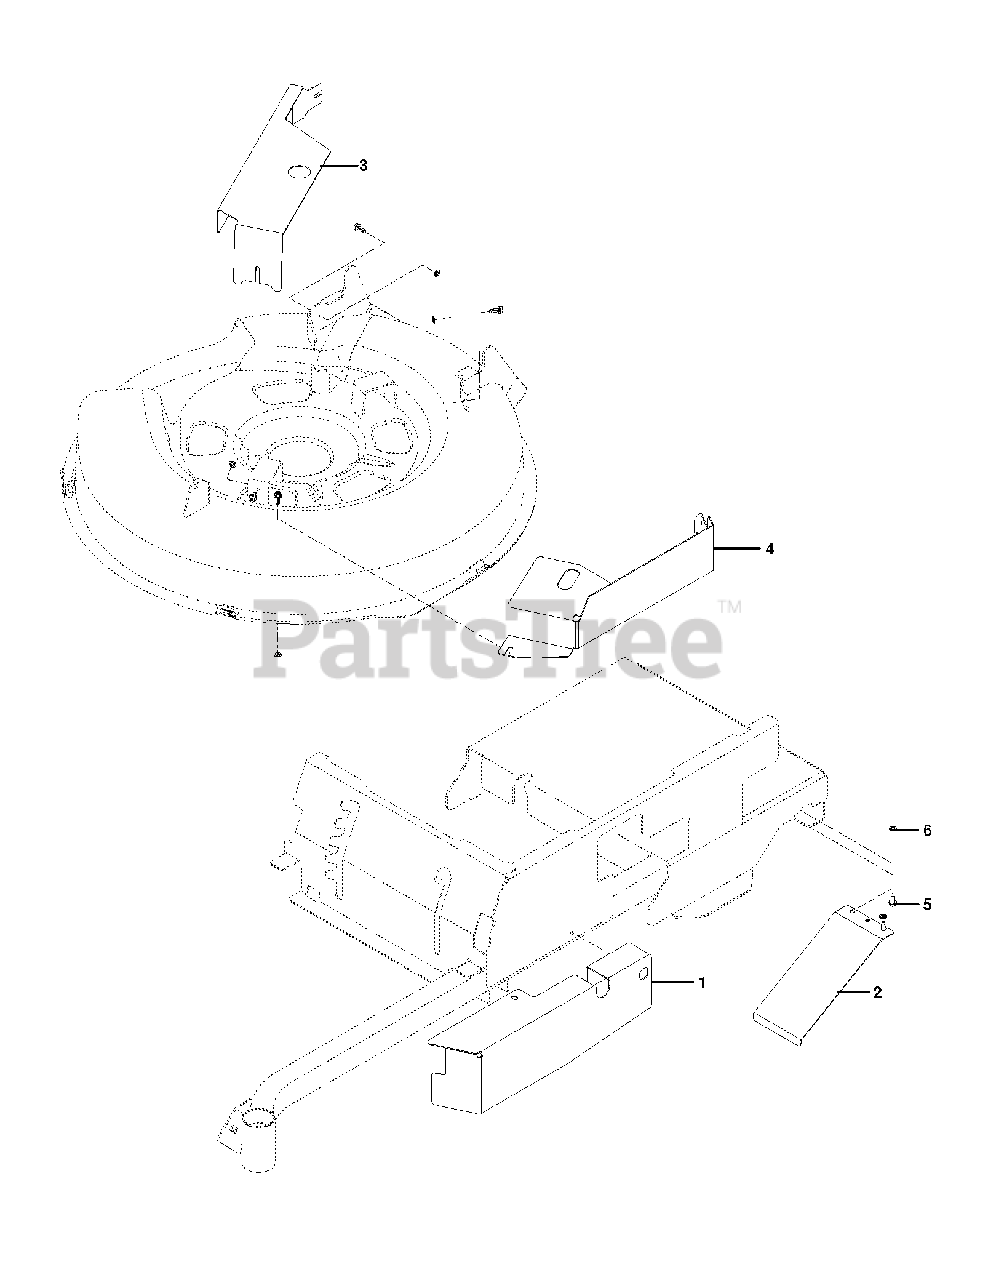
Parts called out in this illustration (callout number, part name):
3	GUARD, SPINDLE BLK
4	GUARD, CLUTCH BLK
5	SCREW- 1/4-20 X 5/8
6	PALNUT 1/4
